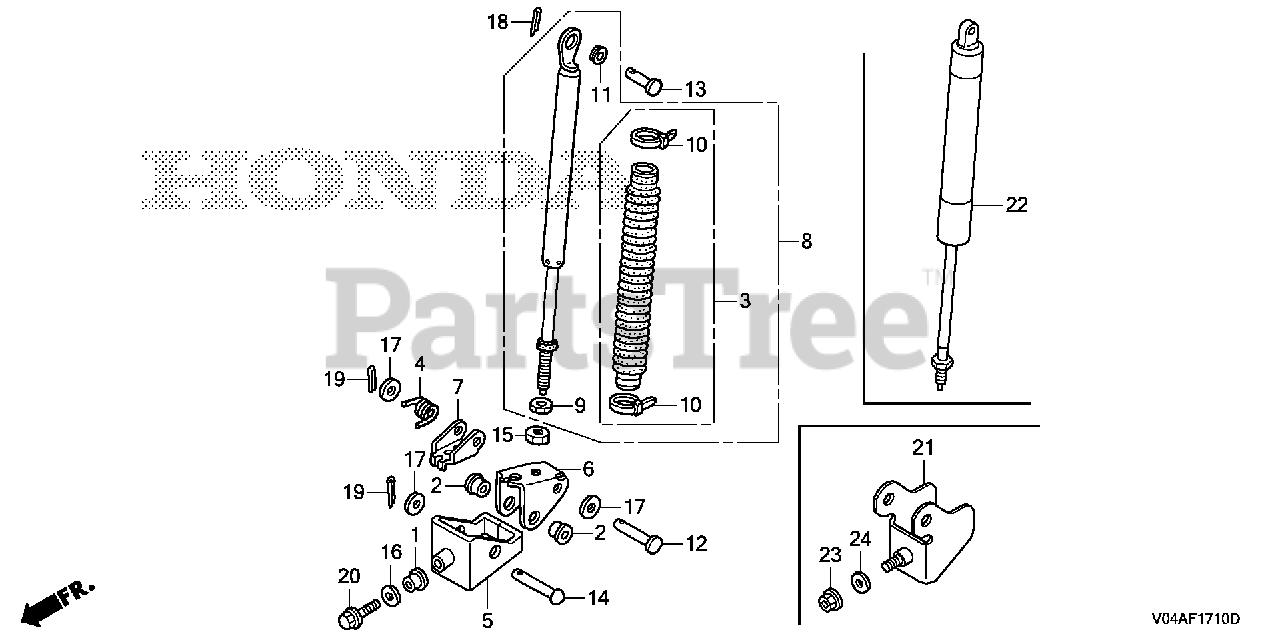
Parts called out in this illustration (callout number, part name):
4	SPRING, HEIGHT ADJUSTING
6	BRACKET, FREE LOCK
7	ARM, PUSH ROD
12	PIN (10X37)
13	PIN (7.2X20)
14	PIN (10X47)
17	WASHER, PLAIN (10MM)
18	PIN, COTTER (2.0X15)
19	PIN, SPLIT (2.5X18)
21	BRACKET, ROLLING
22	LOCK, HEIGHT ADJUSTING FREE
23	NUT, FLANGE (8MM)
24	WASHER, PLAIN (8MM)
